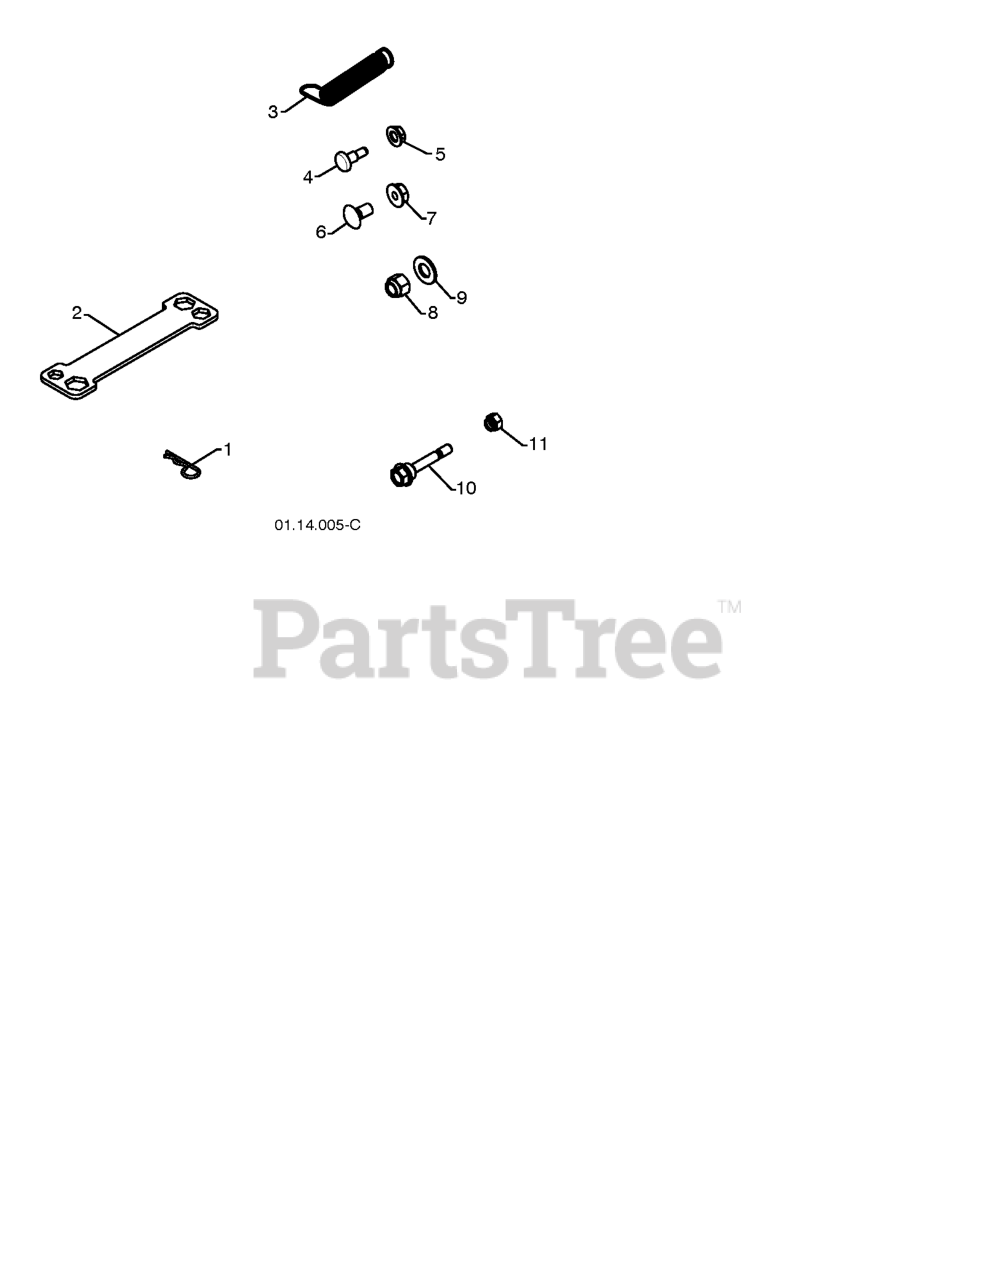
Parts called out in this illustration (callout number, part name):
1	SPRING RETAINER
2	WRENCH.SNOWTHROWER.ZINC.YZ
3	SPRING.DEFLECTOR.REM.CHUTE
4	BOLT, SHOULDER
5	NUT.HEX.FLANGE.1/4
6	BOLT
7	NUT.LOCK.5/16-18
8	NUT
9	WASHER
10	BOLT.SHOULDER.SHEAR.1/4-20.
11	LOCKNUT.NYLOC.1/4-20
